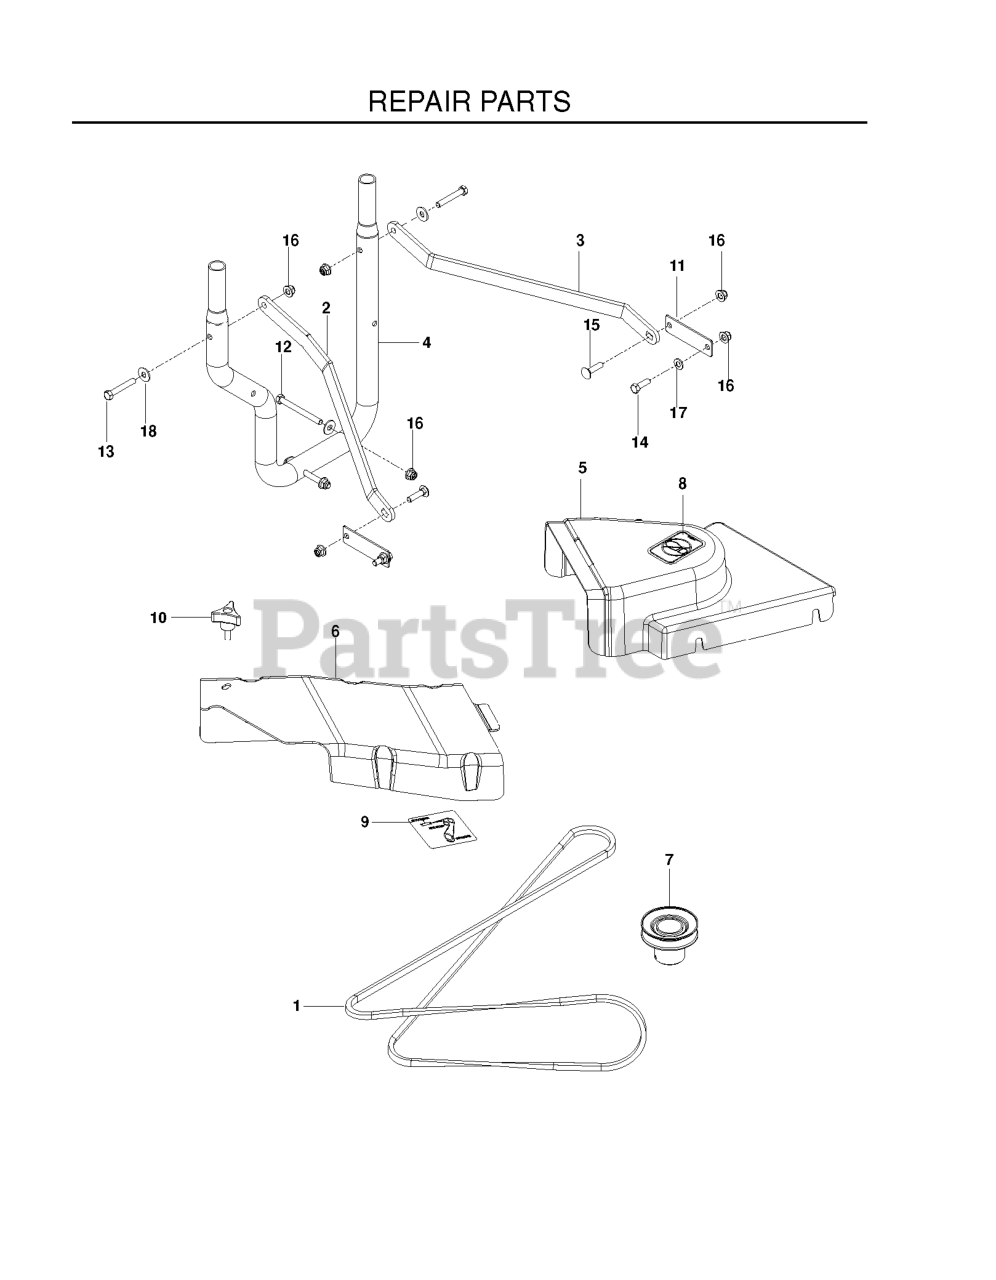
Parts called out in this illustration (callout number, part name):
1	BELT, 48/52"
2	STRAP, SUPPORT, RT PTD
3	STRAP, SUPPORT, LT PTD
4	MOUNT.TUBE.COLLECTIONS
5	SHIELD, BELT, 52"
6	COVER, BELT
7	PULLEY, 52"
8	DECAL, NO STEP
9	DECAL, BELT ROUTING
10	KNOB W/STUD
11	REINFORCEMENT PLATE BLK
12	HCS 5/16-18 X 3 1/4
13	HCS 5/16-18X2
14	HCS 5/16C X 1
15	BOLT, CARRIAGE 5/16X1-1/4
16	5/16-18 NYLOC FLANGE NUT
17	FLAT WASHER 5/16 SAE
18	WASHER 5/16 FLAT
